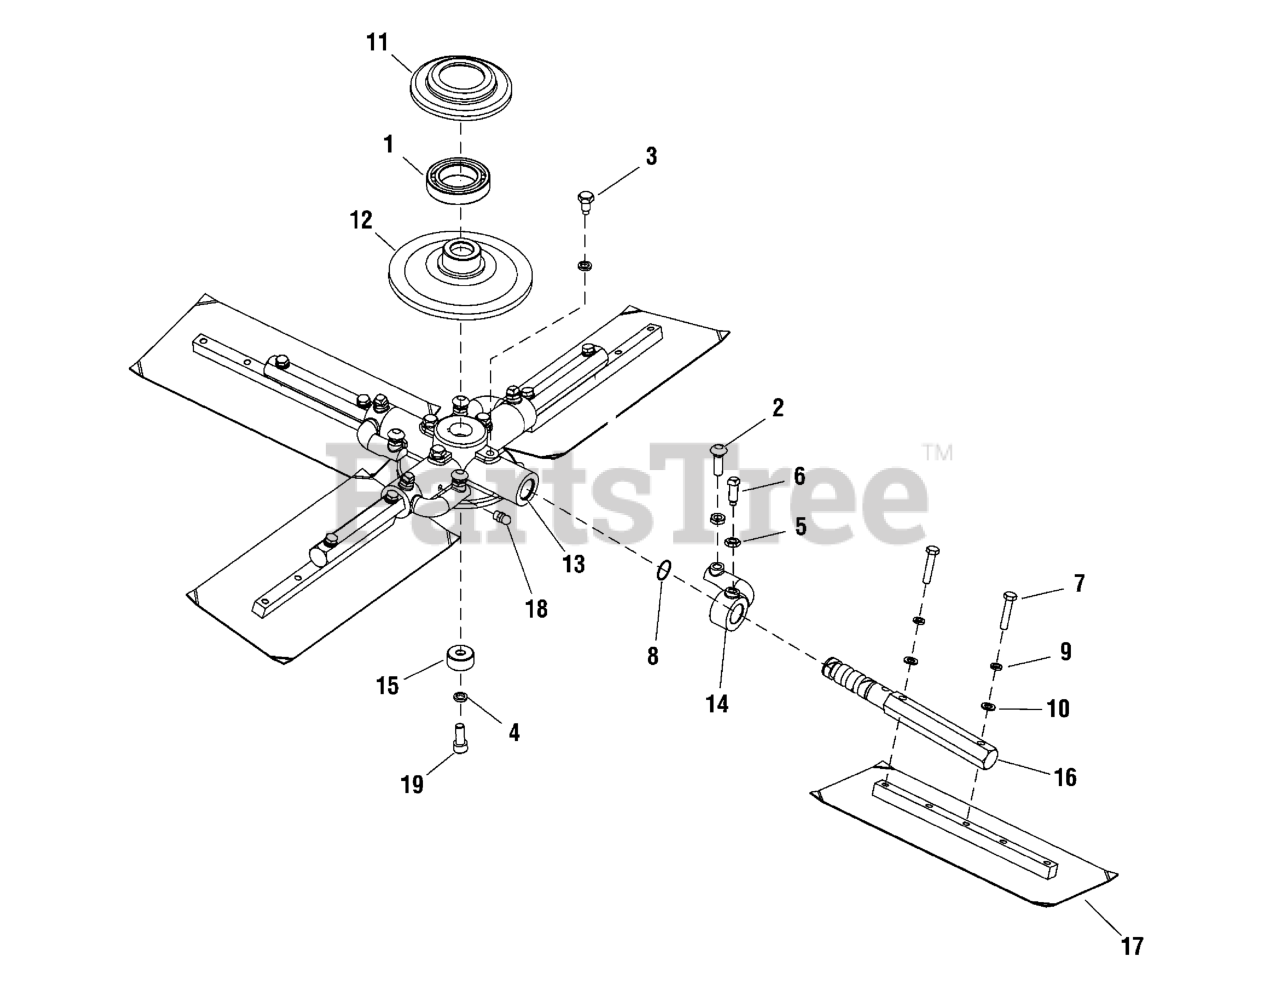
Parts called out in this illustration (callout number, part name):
1	BALL BEARING, Deep Groove
2	BOLT, Cup Head, M10 x 35
3	BOLT, Hex, M10 x 20
4	WASHER, Spring
5	NUT, M10
6	BOLT, Hex Head, M8 x 40
7	O-RING
8	WASHER, Spring
9	WASHER, Spring
10	WASHER, Plain
11	COVER, Platen
12	PLATEN
13	CROSS BASE
15	PACKING SET
16	BRACKET, Blade
17	BLADE ASSEMBLY
18	OIL PLUG, M10 x 1
19	SCREW, Hex Socket Head, M10 x 25
